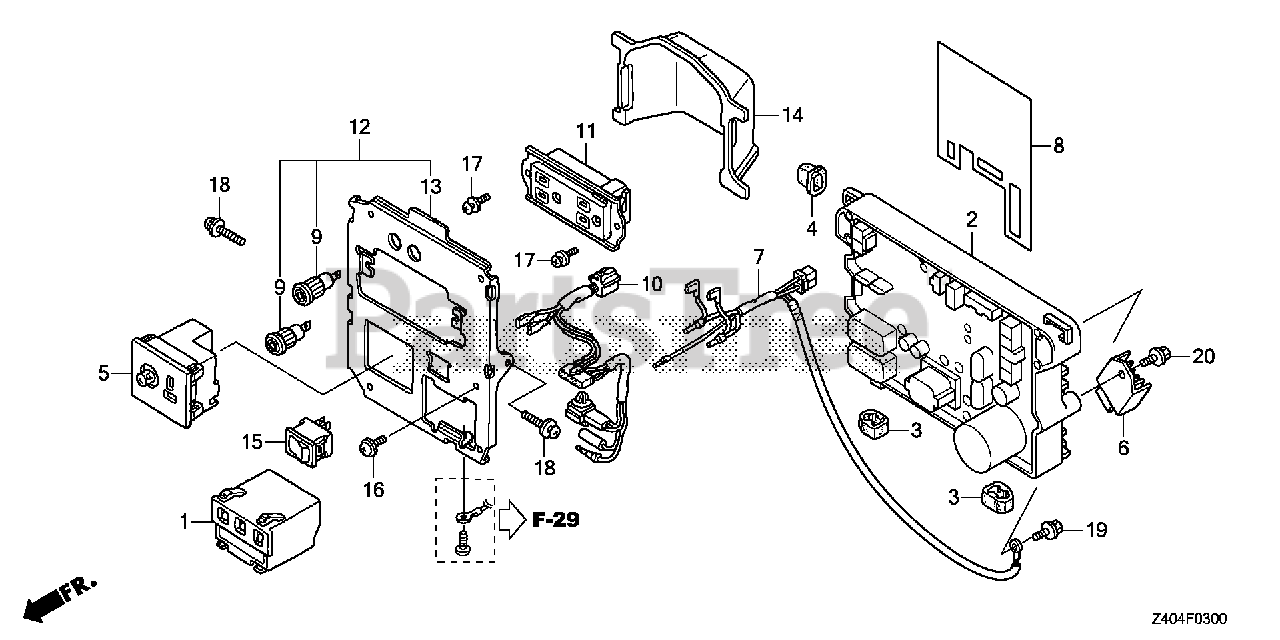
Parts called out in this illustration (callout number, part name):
1	SPARK UNIT
2	INVERTER UNIT
3	RUBBER A, INVERTER
4	RUBBER B, INVERTER
5	RECEPTACLE, D.C.
6	RECTIFIER ASSY.
7	SUB-WIRE HARNESS ASSY.
8	SHEET, WATERPROOF
9	SOCKET, COMPOSITE
10	WIRE HARNESS ASSY., CONTROL
11	RECEPTACLE ASSY. (15A/125V)
12	PANEL, CONTROL
13	PANEL, CONTROL
14	COVER, CONTROL PANEL
15	SWITCH, AUTO-THROTTLE
15	SWITCH, AUTO-THROTTLE (OTAX)
16	SCREW, PAN (5X12)
17	SCREW-WASHER (4X6)
18	SCREW-WASHER (5X20)
19	BOLT, FLANGE (6X10)
20	BOLT, FLANGE (6X12)
